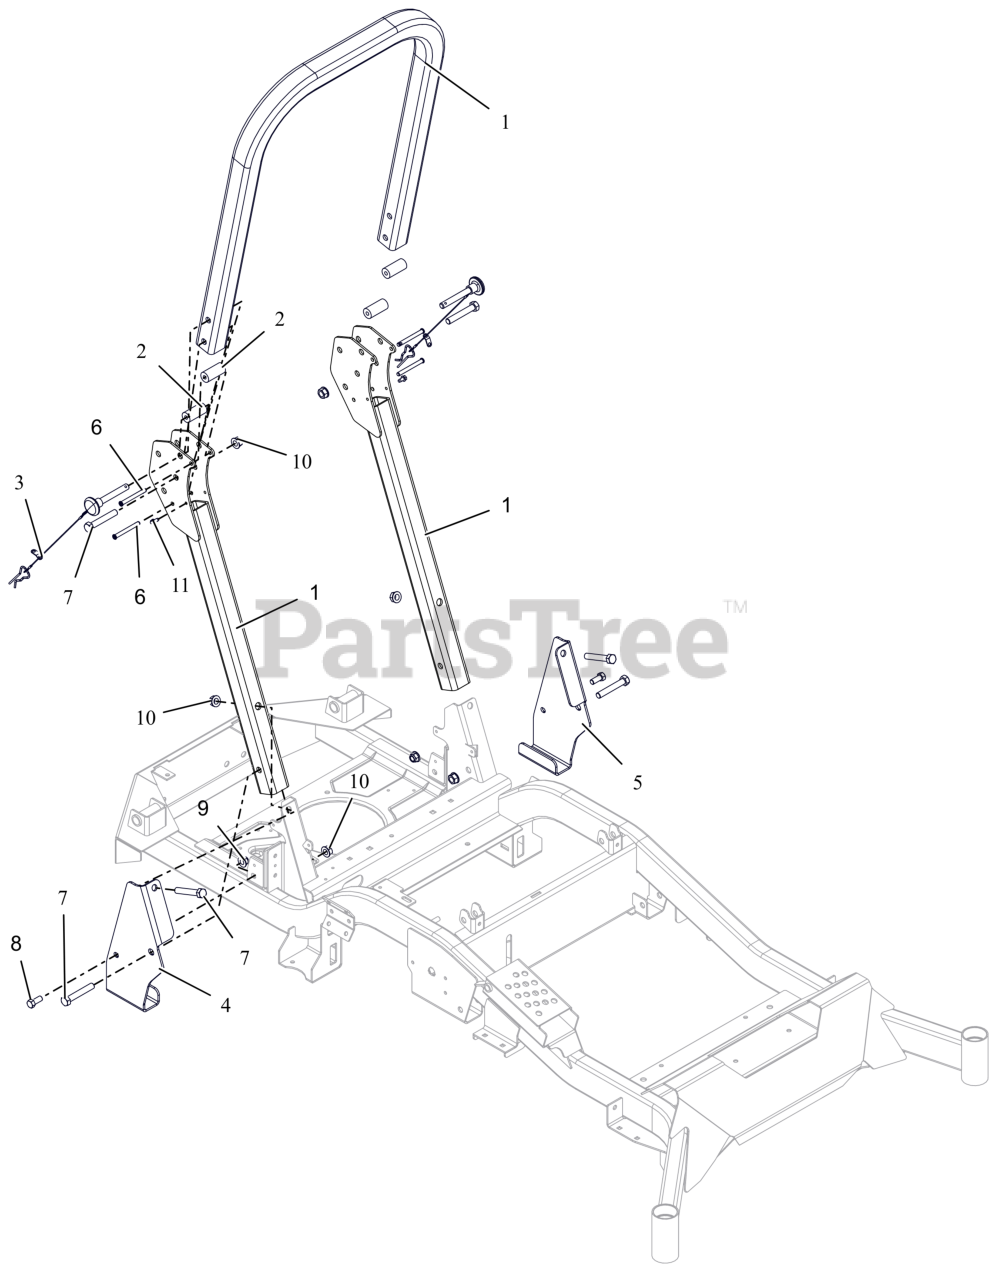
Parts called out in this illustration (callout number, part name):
1	ROPS,PROTURN Z REPLACEMENT-TALL
2	BUMPER, ROPS ANTI-VIBRATION
3	PIN, ROPS W/LANYARD
4	BRKT, ROPS SUPPORT - RH
5	BRKT, ROPS SUPPORT -LH
6	PIN, SLIC .312 X 2.57
7	BLT, HEX .50-13X3.00 G5 ZCC
8	BLT, HEX .44-14X1.00 G5 ZCC
9	NUT, LK-NYL-FLG .44-14 GR5 ZC120
10	NUT-LK-CTR-FLG .500-13 GG ZCC
11	SCR-TAP .25-20X.50 HWH ZCC
